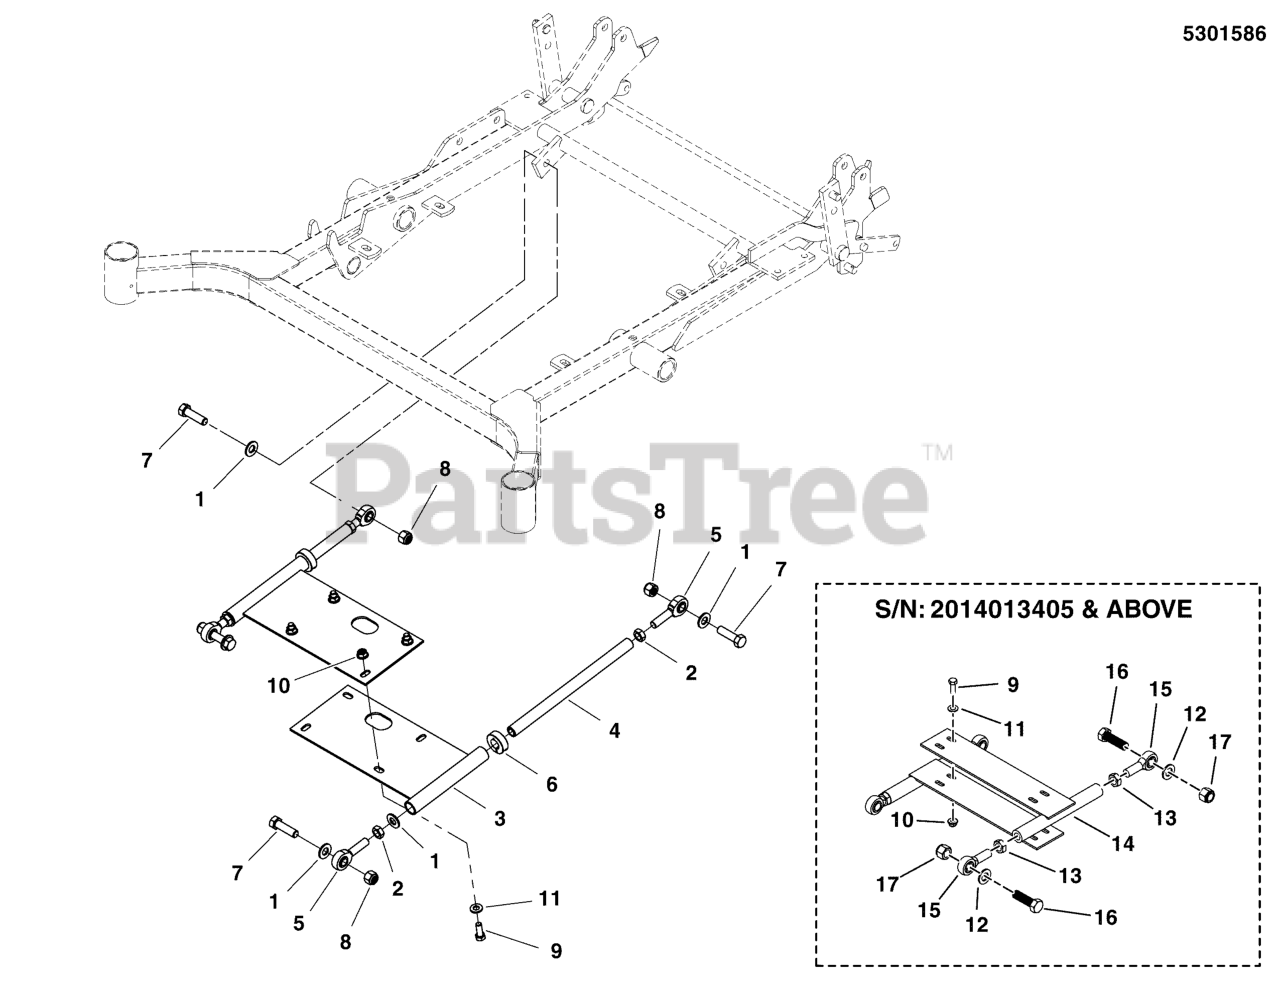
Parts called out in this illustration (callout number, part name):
1	WASHER, 1/2 SAE
2	NUT, 1/2-20 HEX JAM
3	WELD, DECK STABILIZER - RED
4	SHAFT, DECK STABILIZER
5	BALL JOINT, 1/2-20, MALE
6	COLLAR, 3/4 SPLIT
7	BOLT, 1/2-20 X 1-3/4" GD8 CZ
8	NUT, Hex, Nylon Lock, 1/2-20
9	BOLT, 3/8-16 X 1" GD5 CZ
10	NUT, 3/8-16 HEX SERRATED FLANGE
11	WASHER, 3/8 SAE
12	WASHER, 5/8 SAE
13	NUT, 5/8-18, HEX JAM
14	WELD, DECK STABILIZER - RED
15	BALL JOINT, 5/8-18, MALE
16	BOLT, HEX, 5/8-11 X 21/2, GD5, CZ
17	NUT, 5/8-11 HEX NYLON LOCK
